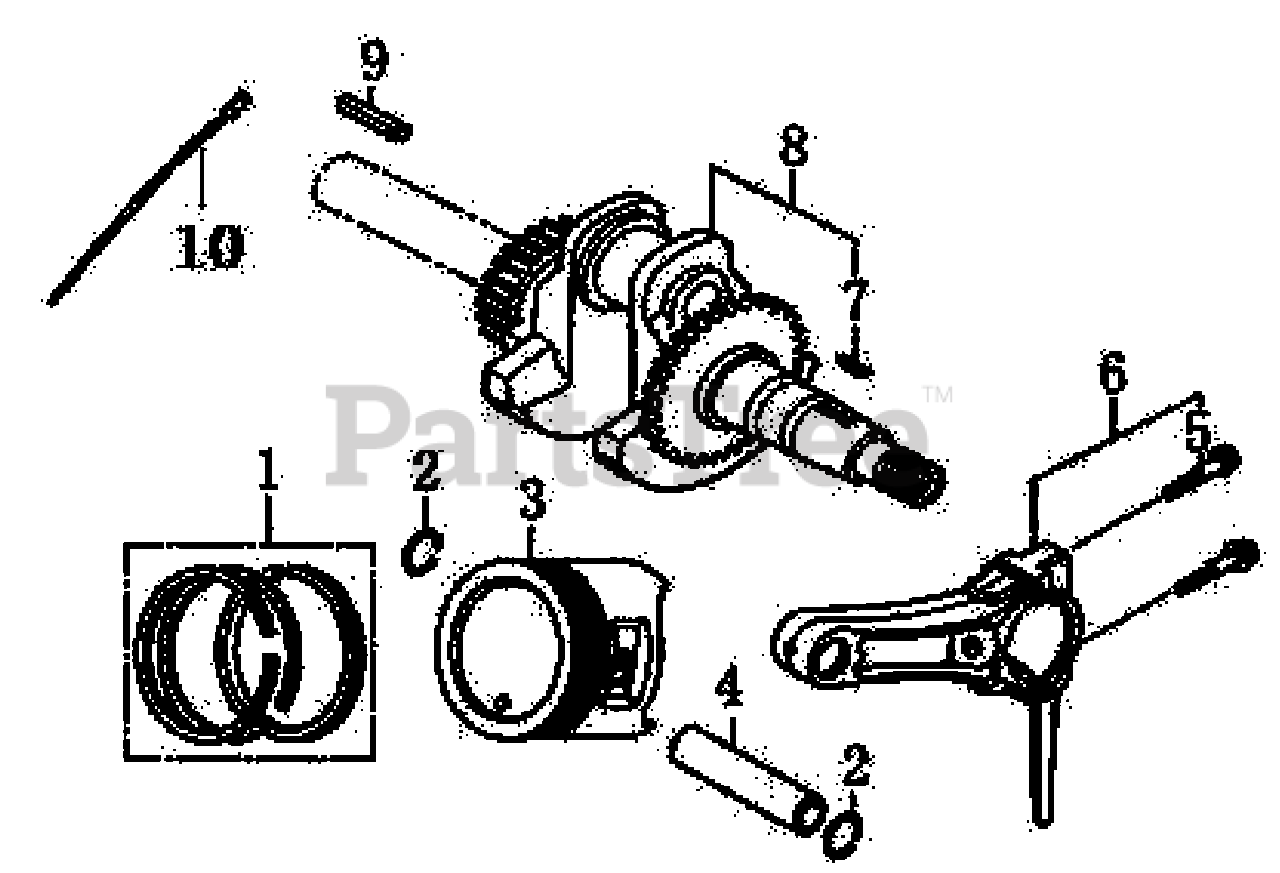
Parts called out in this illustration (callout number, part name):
2	CLIP, PISTON PIN
4	PIN, PISTON
5	BOLT, CONNECTING ROD
6	ROD ASSEMBLY, CONNECTING
7	KEY, SPECIAL WOOD FORD
8	CRANKSHAFT ASSEMBLY
9	KEY, CRANKSHAFT
10	HOOP STRIP
